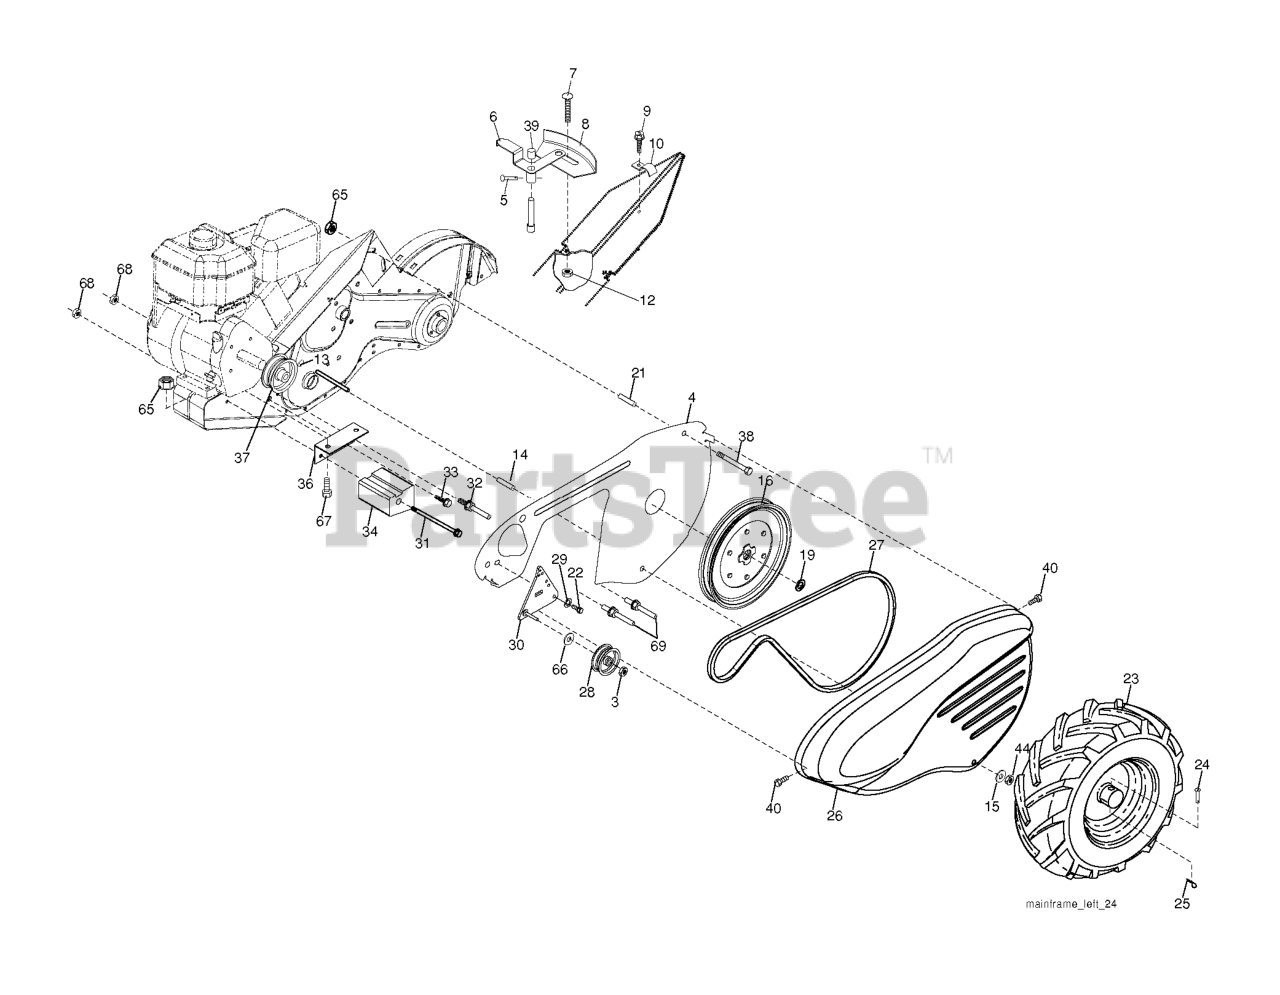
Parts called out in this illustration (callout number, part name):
3	LOCKNUT
4	SHIELD
5	PIN.SPIROL.FLARED
6	LEVER ASM CRT
8	PANEL.INDICATOR.SHIFT.BLACK
9	TAPPING SCREW
10	CONDUIT.CLIP.PLATED
12	NUT
14	SPACER CRT
15	WASHER
16	SHEAVE, TRANSMISSION
19	RETAINING RING LT
21	SPACER-SPLIT.327 X .42
23	TIRE.13X5-6.CHEVRON.TILLER
24	RIVET,DRILLED
25	RETAINER M
26	RP BELT GUARD
27	V-BELT
28	PULLEY-IDLER TI
30	BRACKET.ASM.IDLER.BLACK
32	SHIFT ARM CRT
33	BOLT
34	COUNTERWEIGHT, RH
36	BRACKET LH CRT
37	RP.ENGINE PULLEY
38	BOLT
39	CAP.PLUNGER.BLACK
40	SCREW.HEX.WSH.SLT.#10-24X.50
44	NUT.71038.31-18.HEX.NYLOCK
65	LOCKNUT-FLANGE 5/16-18
66	WASHER
67	BOLT
69	KEEPER.BELT.ENGINE
